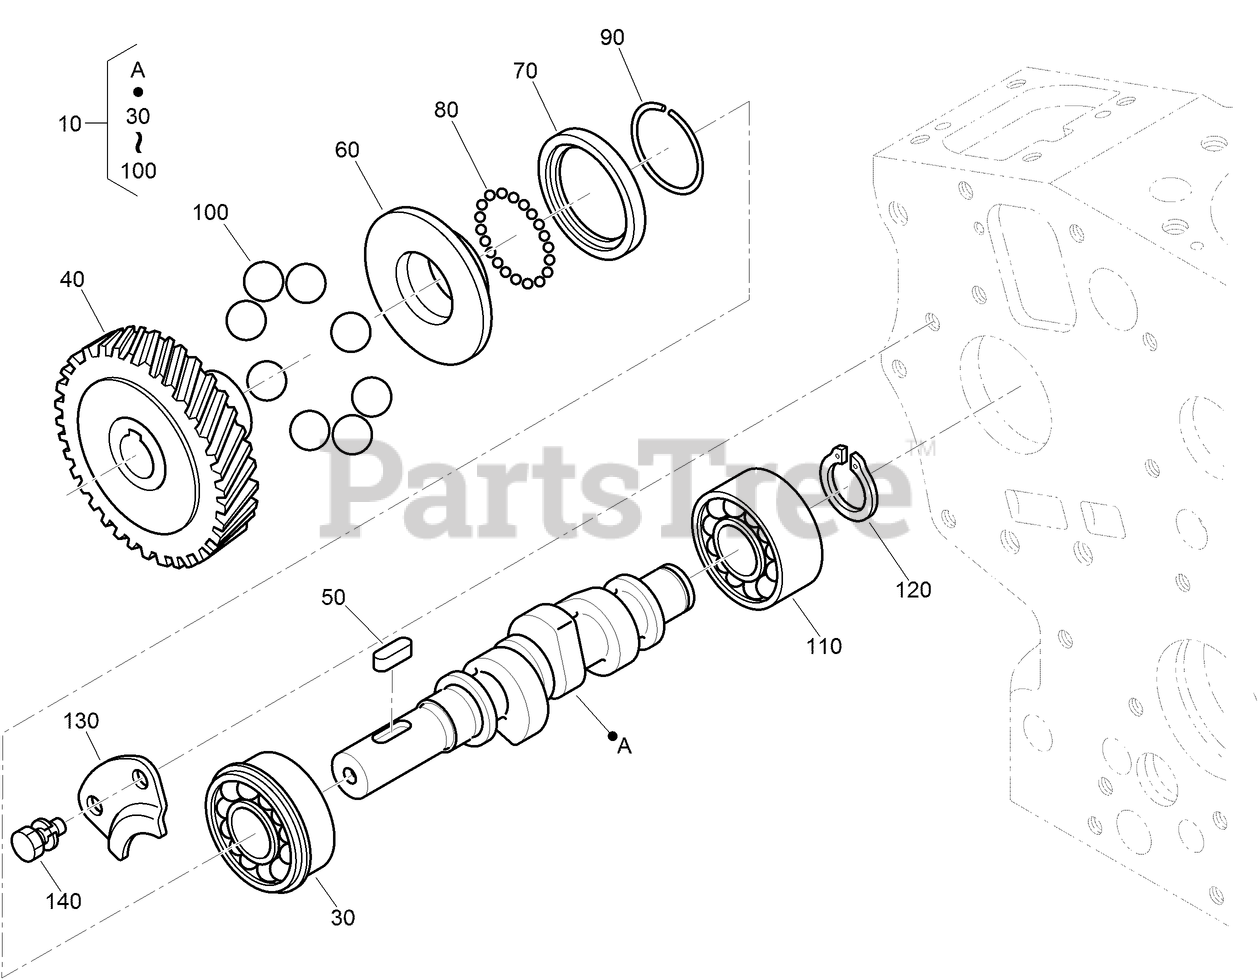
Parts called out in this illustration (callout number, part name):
10	FUEL CAMSHAFT ASM
30	BEARING-BALL
40	GEAR-PUMP, INJECTION
50	KEY-FEATHER
60	SLEEVE-GOVERNOR
70	CASE-BALL, GOVERNOR
90	CIRC-CLIP
110	BEARING-BALL
120	CIRC-CLIP, EXTERNAL
130	STOPPER-FUEL, CAMSHAFT
